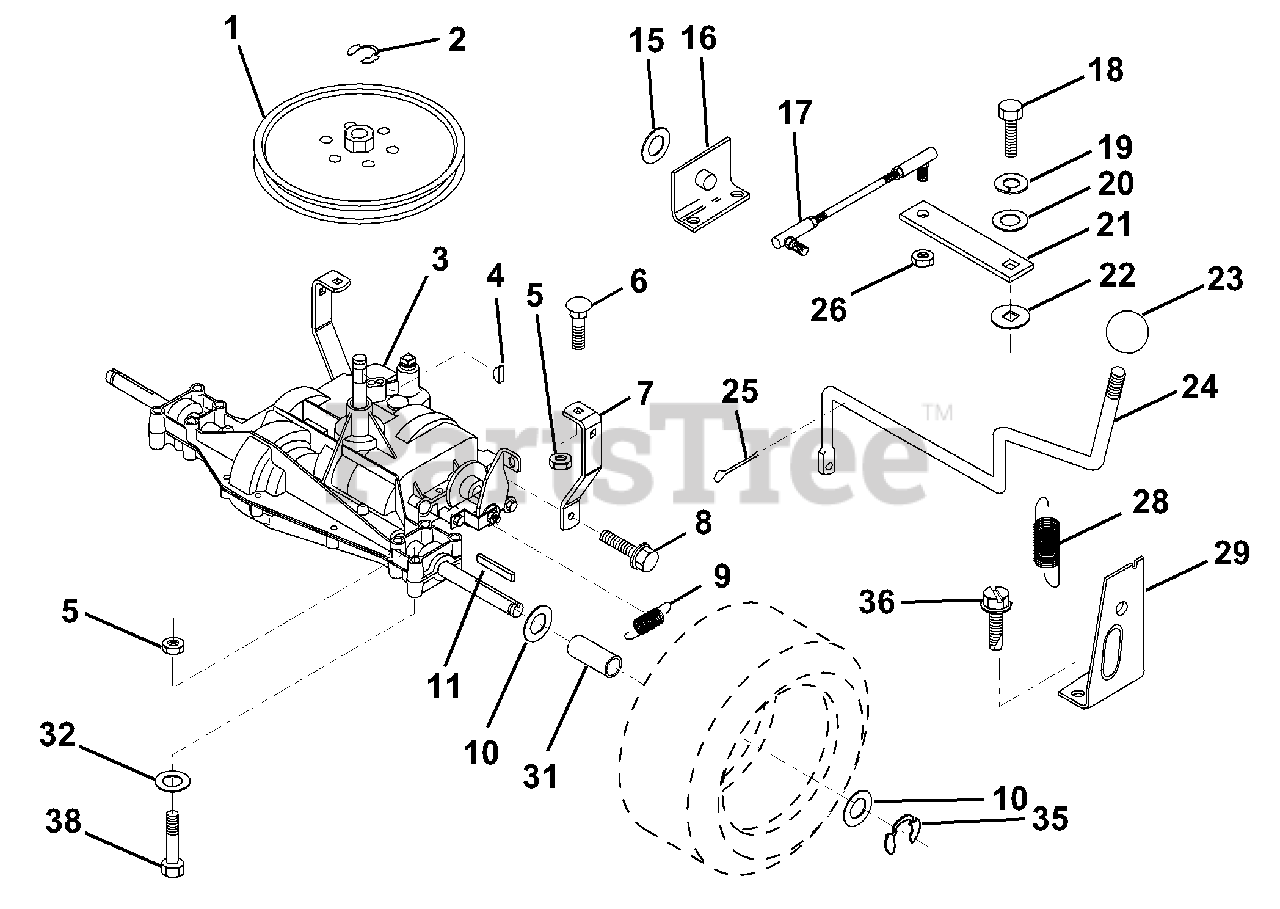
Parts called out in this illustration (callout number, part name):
2	Ring, Retainer
4	Key, Woodruff #9
5	Nut, Crownlock 5/16-18
6	Bolt, Carriage 5/16-18 UNC x 3/4
7	Strap, Torque
8	Screw 5/16-18 x 3/4
9	Spring, Brake
10	Washer 25/32 x 1-1/4 x 16 Ga.
11	Key, Square
15	Washer 17/32 x 1 x 16 Ga.
16	Support Handle Shift LH
17	Link, Shift
18	Bolt, Fin Hex 1/4-28 UNF x 3/4 Gr. 8
19	Washer, Lock 1/4
20	Washer 9/32 x 3/4 x 10 Ga.
21	Arm, Shift
22	Washer, Shift Plate
23	Knob, Rd 1/2-13
25	Pin, Cotter 1/8 x 1
26	Locknut 5/16-24 UNF
28	Extension, Spring
29	Support Handle Shift RH
31	Spacer Axle
32	Washer 11/32 x 11/16 x 16
36	Screw, Thd Cut 1/4-20 x 1/2
38	Bolt, Hex Hd 5/16-18 x 2-3/4
